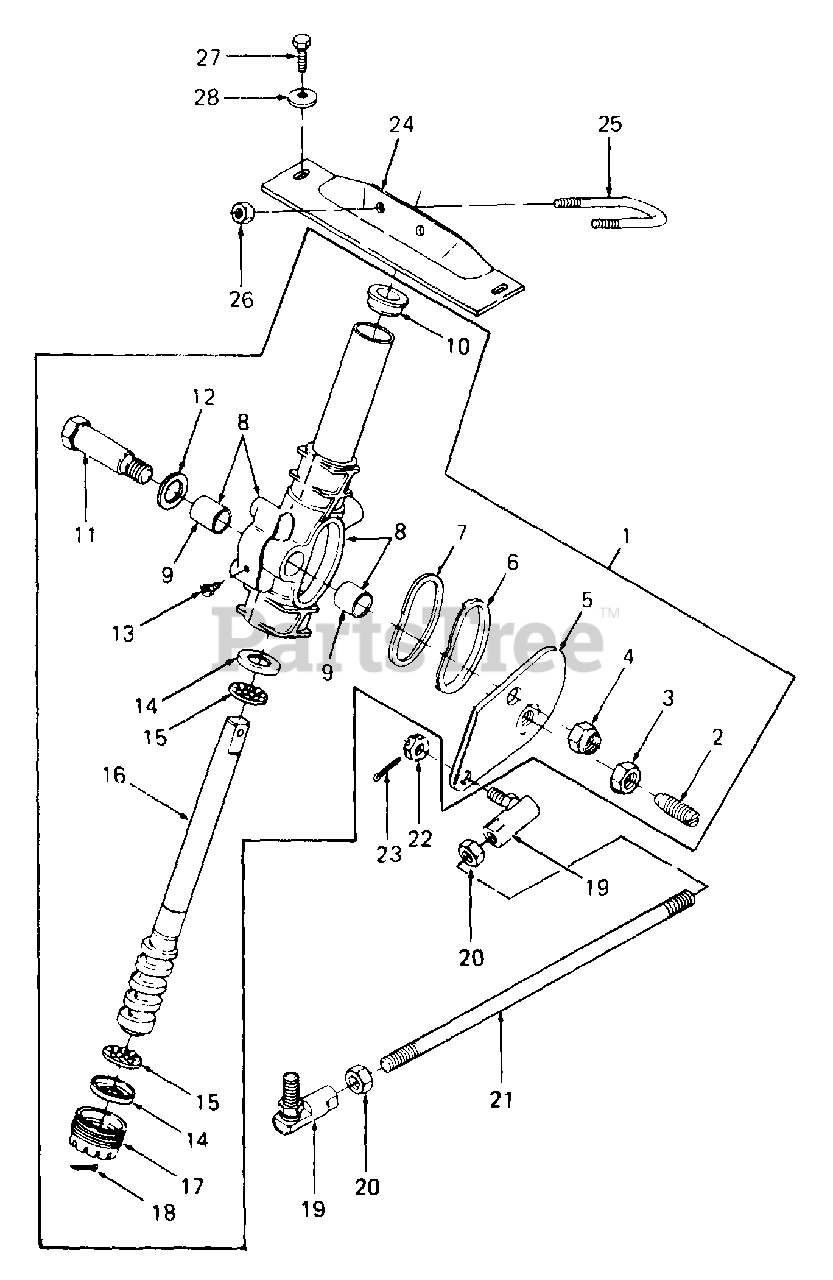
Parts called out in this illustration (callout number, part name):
1	Steering Gear Assy
2	Follower, Cam
3	Nut, Hex Jam, 9/16-18
4	Nut, Hex Crown Lock, 5/8-18
5	Arm, Steering
6	Retainer, Seal
7	Seal
8	Housing/Tube Assy
10	Bearing, Column
11	Shaft, Pivot
12	Washer, Flat, .781 X 1.25 X .027 Thk
13	Fitting, Lube, 45 Deg 1/4-28 Taper
14	Cup, Bearing
15	Retainer Assy, Ball
16	Shaft/Cam Assy
17	Plug, Adjusting
18	Pin, Cotter, 1/8 Dia X .45 Lg
19	Ball Joint
20	Nut, Hex Jam, 1/2-20 GR5
21	Link, Drag
22	Nut, Hex Castle, 1/2-20 GR5
23	Pin, Cotter, 3/32 Dia X 1.25 Lg
24	Plate, Steering Support
26	Nut, Hex Center lock, 5/16-24
27	Screw, Hex Hd Cutting, 5/16-18 X .75 Lg GR5
28	Washer, Bell, .345 X .88 X .060 Thk
